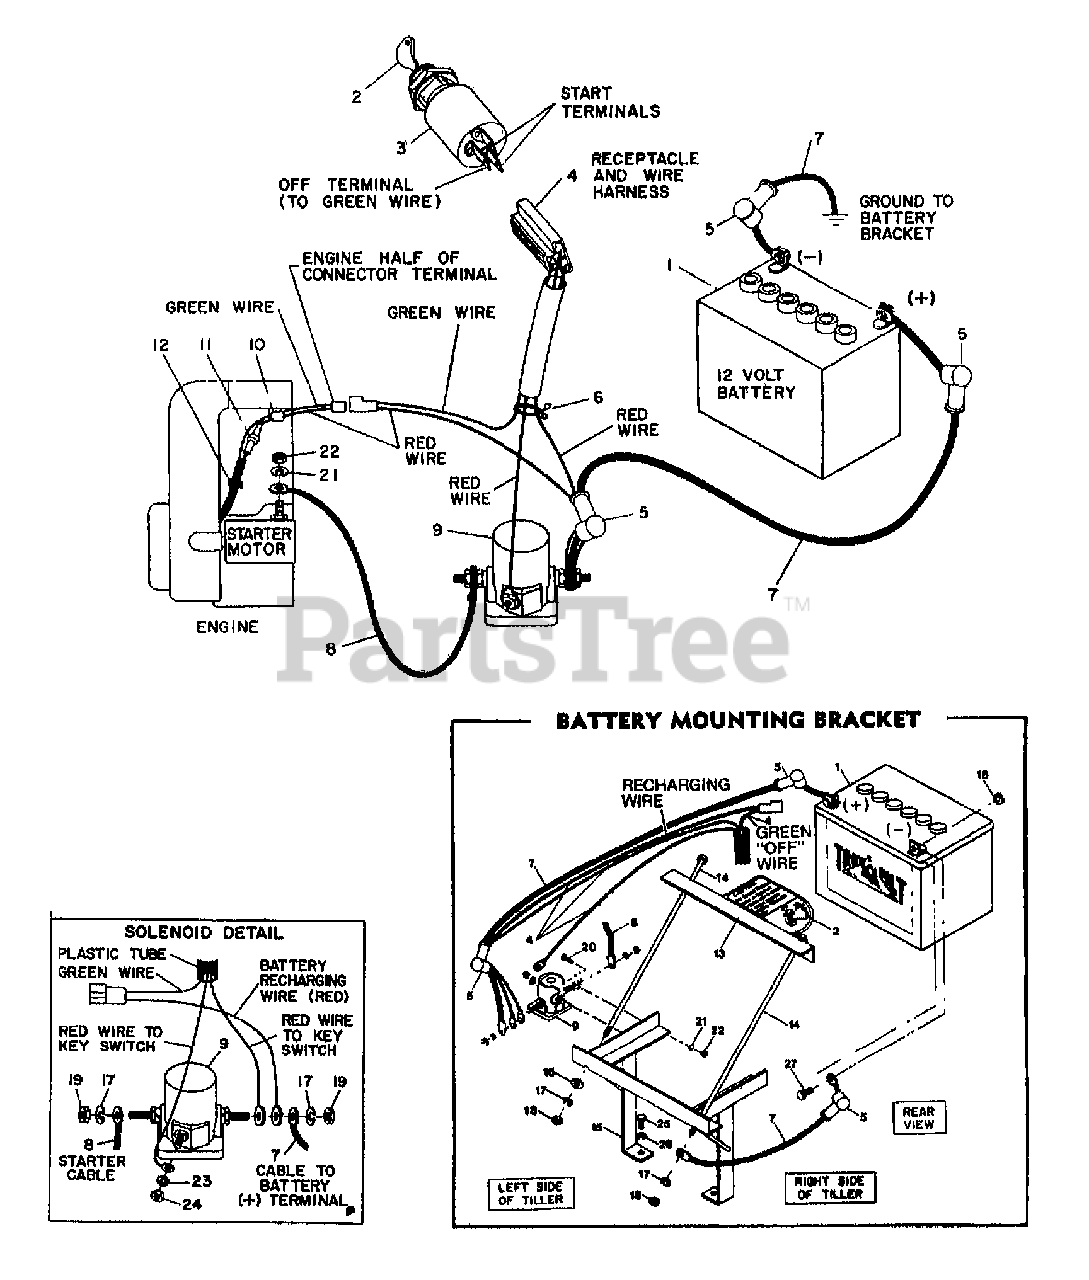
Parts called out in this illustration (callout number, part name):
1	KIT-VENTED BATTERY
2	KEYS(1 PAIR) FOR SWITCH
3	KEYSWITCH W/KEYS
4	HARNESS-WIRE 6HP
6	TIE-TWIST LOCK
7	CABLE-BATTERY
8	CABLE-BATTERY
9	KIT-SOL W/HDW
10	CLIP-SPECIAL
11	FUSE- 6AM, 3AGC
12	DIODE - BATTERY DISCHARGING
13	KEYSWITCH PLATE/CLAMP-WELD
14	SCR-HH 5/16-18 X 9
15	KIT-BATTERY BRKT HORSE
16	WASHER-FLAT 5/16 SAE
17	WASHER-LK .312 ZP
18	NUT-HEX 5/16-18 ZP
19	NUT-HEX 5/16-24
20	SCR-RH 1/4-20 X .75 ZP
21	WASHER-LK .25 ZP
22	NUT-HEX 1/4-20 ZP
23	WASHER-EXTERNAL TOOTH 1
24	NUT-HH M10-32X.125
25	BOLT-HH 3/8-16X1.5 FTH ZP
26	WASHER-LK .375 @ DEPL
27	SCR-HHC 5/16-18X.75 GR 5 ZP
